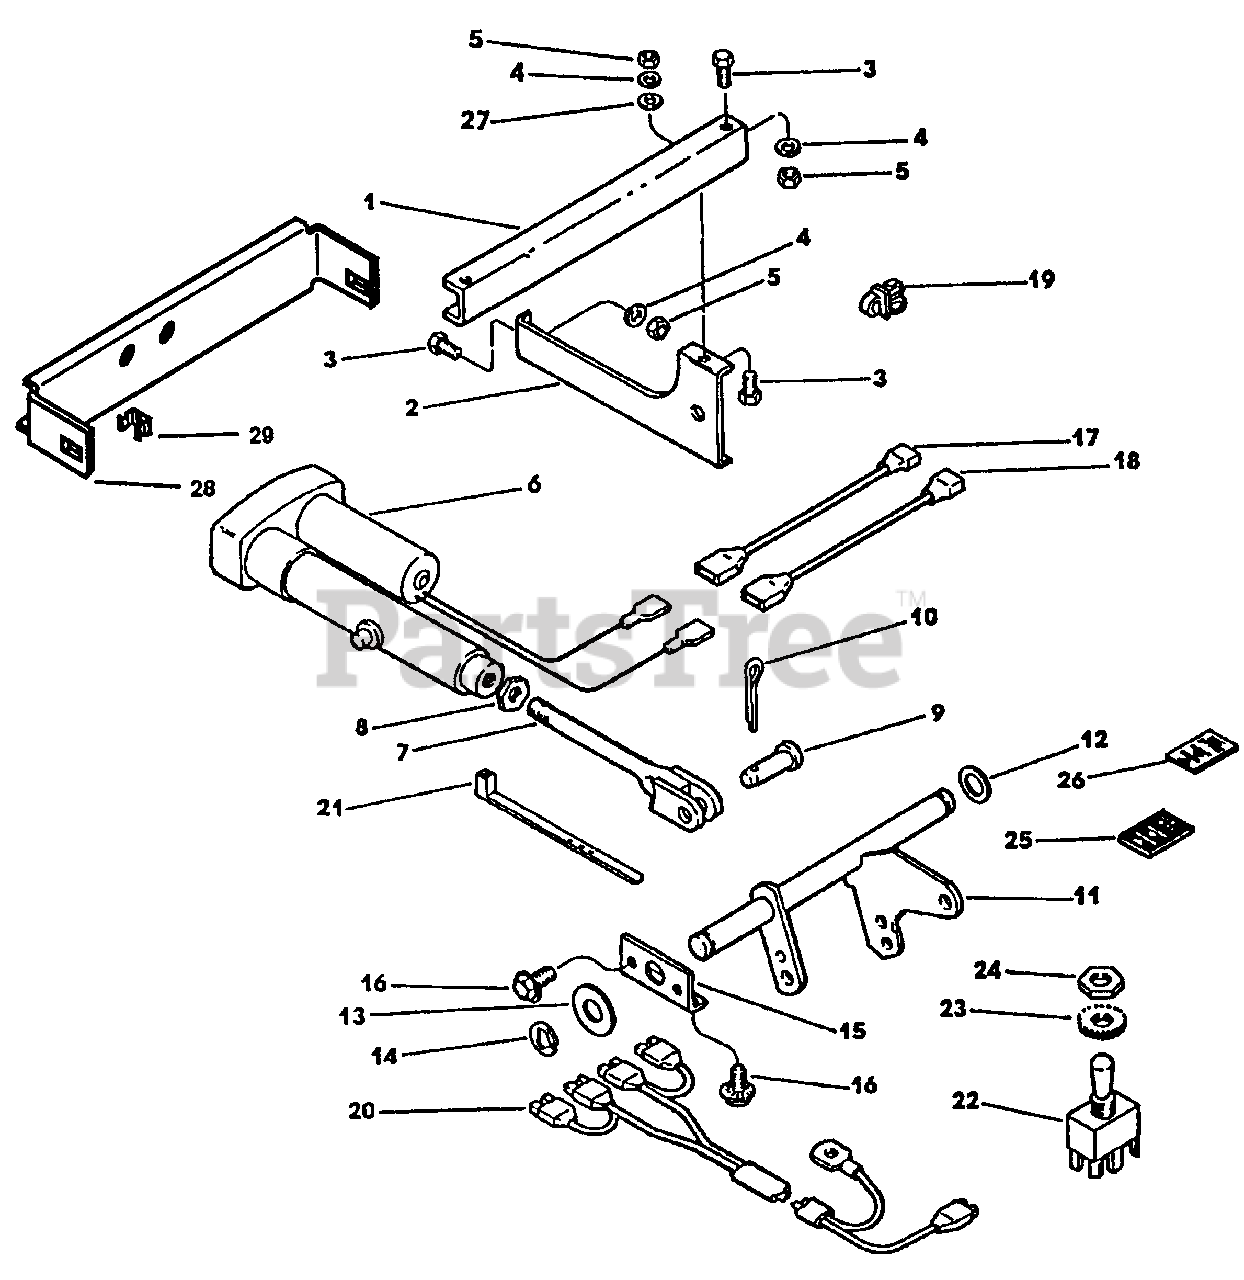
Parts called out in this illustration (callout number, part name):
2	Support
3	Cap Screw, Hex Hd.
4	Washer, Spring Lock
5	Nut, Hex
6	Power Lift Assembly
7	Rod Assembly
8	Nut, Hex
9	Clevis Pin
10	Pin, Cotter
11	Lift Shaft Assembly
14	"E" Ring
15	Lift Bracket
16	Thread Forming Screw, Hex Hd.
17	Wire, Yellow-37"
18	Wire, Red-37"
19	Wire Clip
20	Wiring Harness
21	Cable Tie
22	DPDT Switch
23	Knurled Nut
24	Hex Nut
25	Decal-Lift (White On Black)
26	Decal-Lift (Black On Silver)
27	Washer, Flat
28	Support-Electric Lift
29	Cage Nut
